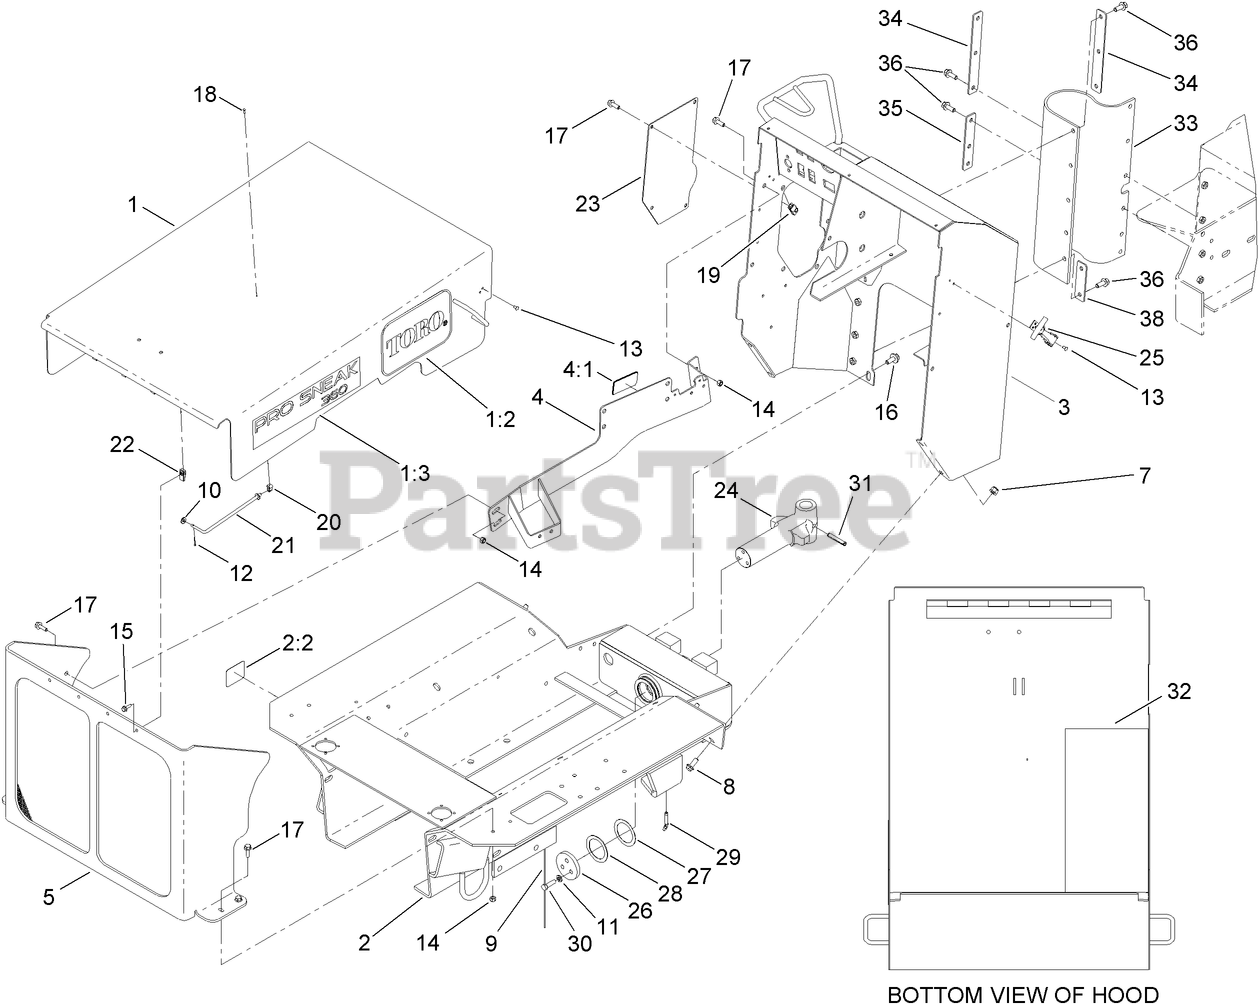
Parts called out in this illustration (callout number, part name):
1	HOOD AND DECAL ASM
1:2	DECAL
2	FRONT FRAME AND DECAL ASM
2:2	DECAL-TIE DOWN
3	CONSOLE AND DECAL ASM
4	CENTER BRACKET AND DECAL ASM
4:1	DECAL-DANGER, STARTING
5	SUPPORT-GRILL AND HOOD
7	NUT-LOCK, NI
8	SCREW-HHF
9	WIRE-STEEL
11	WASHER-LOCK
12	PIN-COTTER
14	NUT-LOCK, NI
15	SCREW-HHF
16	SCREW-HHF
17	SCREW-HHF
18	RIVET
20	HOLDER-PROP, ROD
21	ROD-HOOD
23	PANEL-COVER
24	PIVOT-ARTICULATION
25	LATCH-FLEX, DRAW
27	SHIM-THIN
29	FITTING-GREASE
30	SCREW-HH
31	PIN-SLOTTED, SPRING
32	TAPE-HEAT SHIELD
33	SHIELD, RUBBER
36	SCREW-HHF
